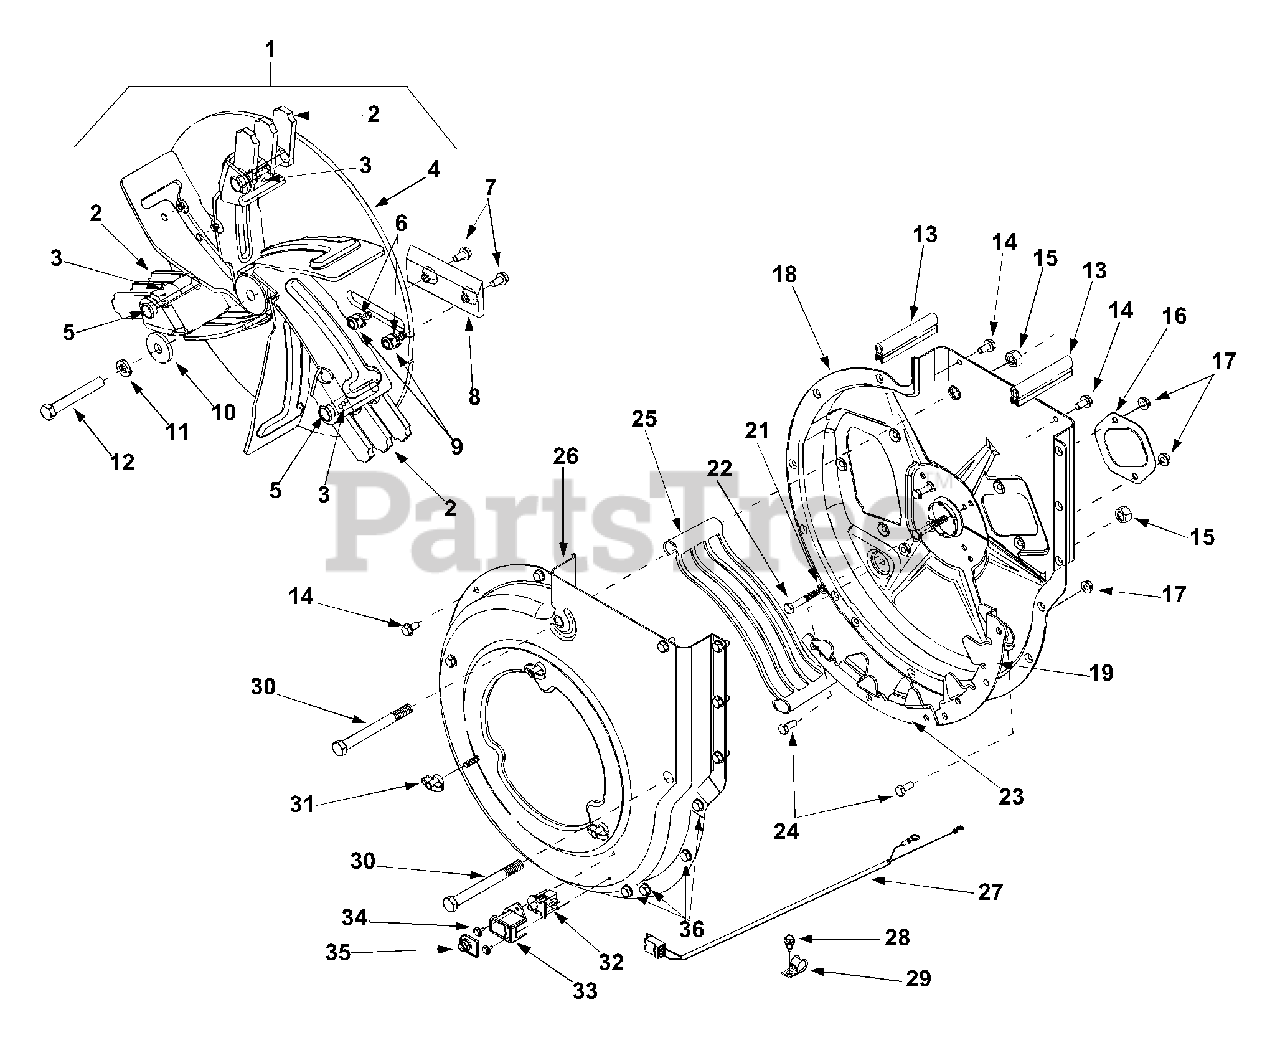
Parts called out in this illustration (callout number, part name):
1	Impeller Assembly: Complete
2	Flail Blade
3	Spiral Pin
4	Impeller Assembly
5	Clevis Pin
6	Lock Washer 5/16
7	Cap Screw 5/16-24 x 1.0
8	Chipper Blade
9	Hex Lock Nut 5/16-24
10	Flat Washer .406 x 1/1/4
11	Lock Washer 3/8
12	Hex Cap Screw 3/8-24 x 2.75
13	Rubber Seal
14	Hex Washer Screw 5/16-18
15	Hex Lock Nut 1/2-13
17	Hex Flange Lock Nut 5/16-18
21	Lock Washer 5/16
22	Hex Cap Screw 5/16-18 x 2
24	Hex Cap Screw 5/16-18 x .75
25	Discharge Screen
27	Wire Harness
28	TT Screw 1/4-20 x 0.625"
30	Hex Cap Screw 1/2-13 x 5.0
31	Knob 5/16-18
32	Switch
33	Safety Switch Mounting Cover
34	Hex Washer Screw
35	Switch Cover
36	LD Screw 5/16-18 x 0.75"
